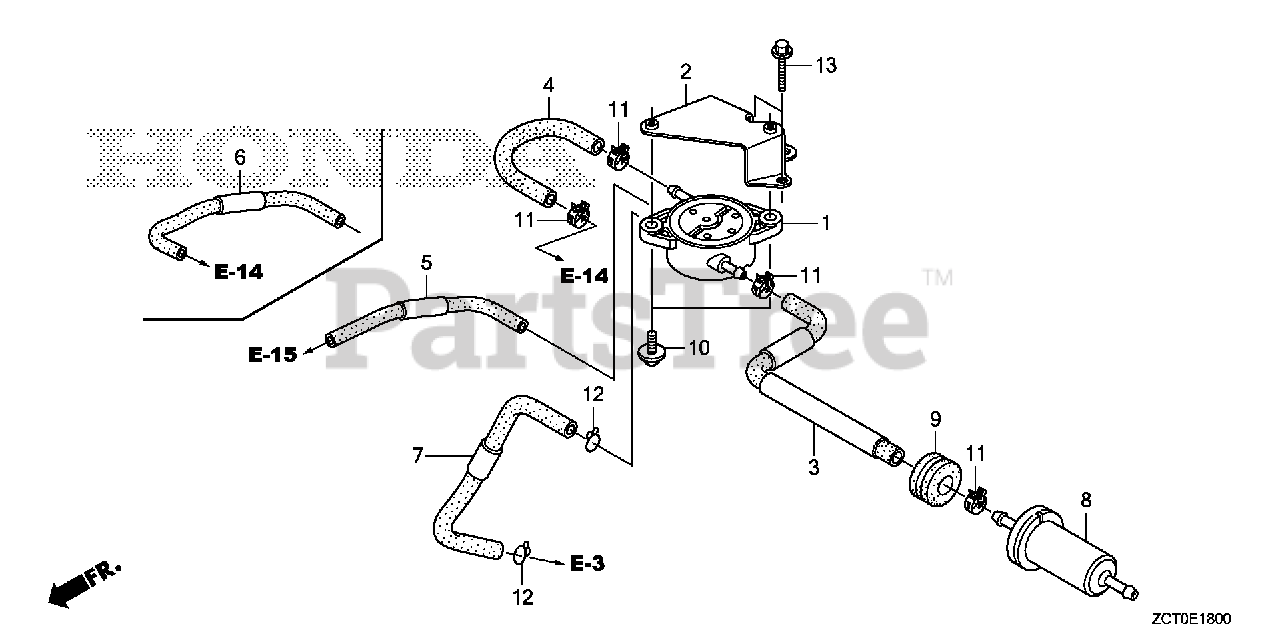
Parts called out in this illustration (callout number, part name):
1	PUMP ASSY., FUEL (MSDS)
2	STAY, FUEL PUMP
3	TUBE A, FUEL (FKM)
4	TUBE B, FUEL (FKM)
5	TUBE, PURGE
7	TUBE, DIAPHRAGM
8	STRAINER, FUEL
9	RUBBER, RR. FENDER
10	SCREW, TRUSS (6X12)
11	CLAMP, TUBE (D10)
12	CLIP, TUBE (C11)
13	BOLT, FLANGE (6X14)
